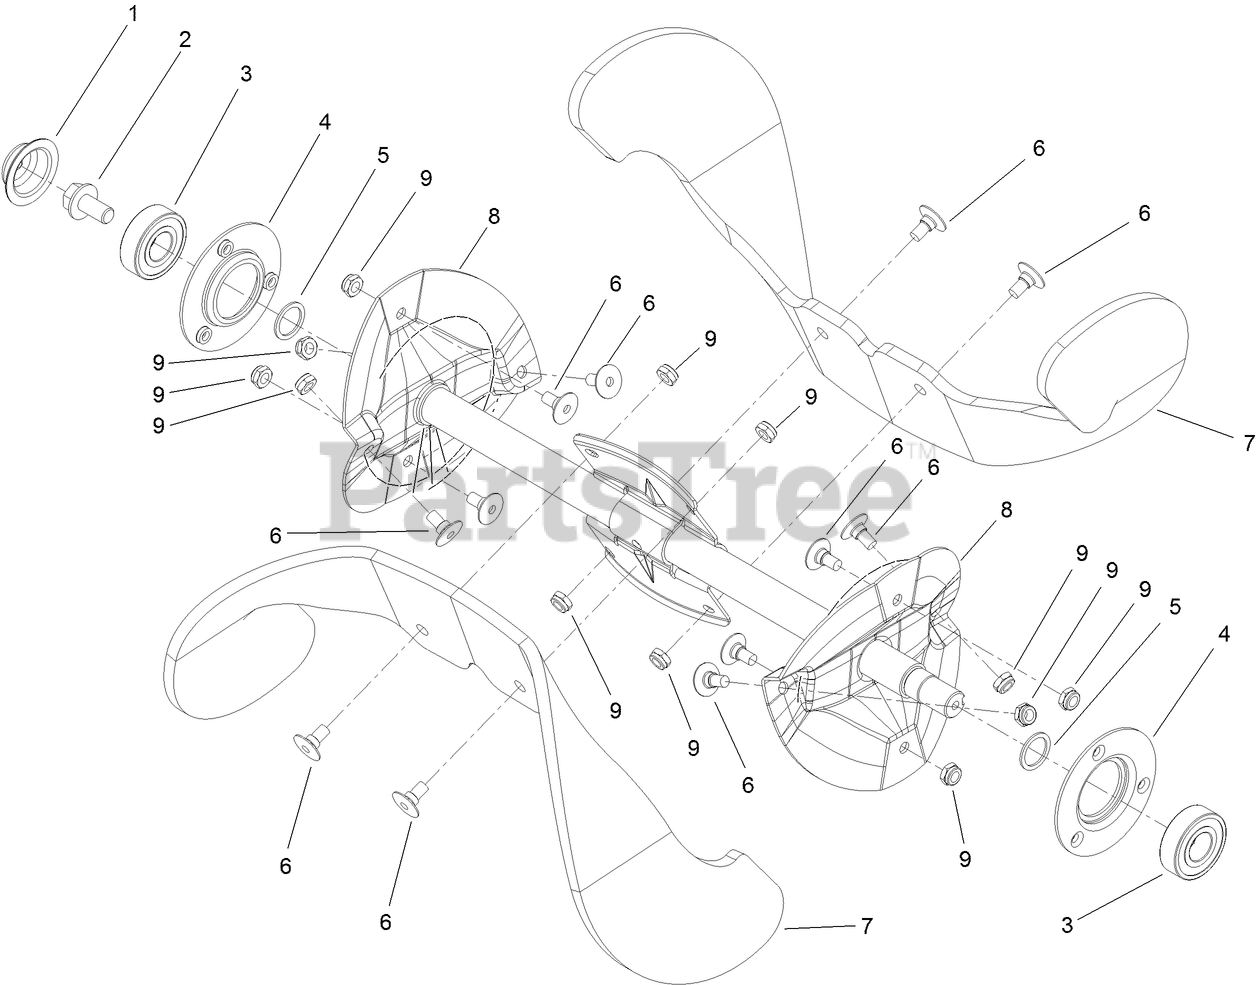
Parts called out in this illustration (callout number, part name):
1	CAP-SIDEPLATE, RH
2	SCREW-HWH
3	BEARING-BALL
4	FLANGE-BEARING
5	WASHER-THRUST
6	SCREW
7	BLADE-ROTOR
8	ROTOR ASM
9	NUT-LOCK, NI
